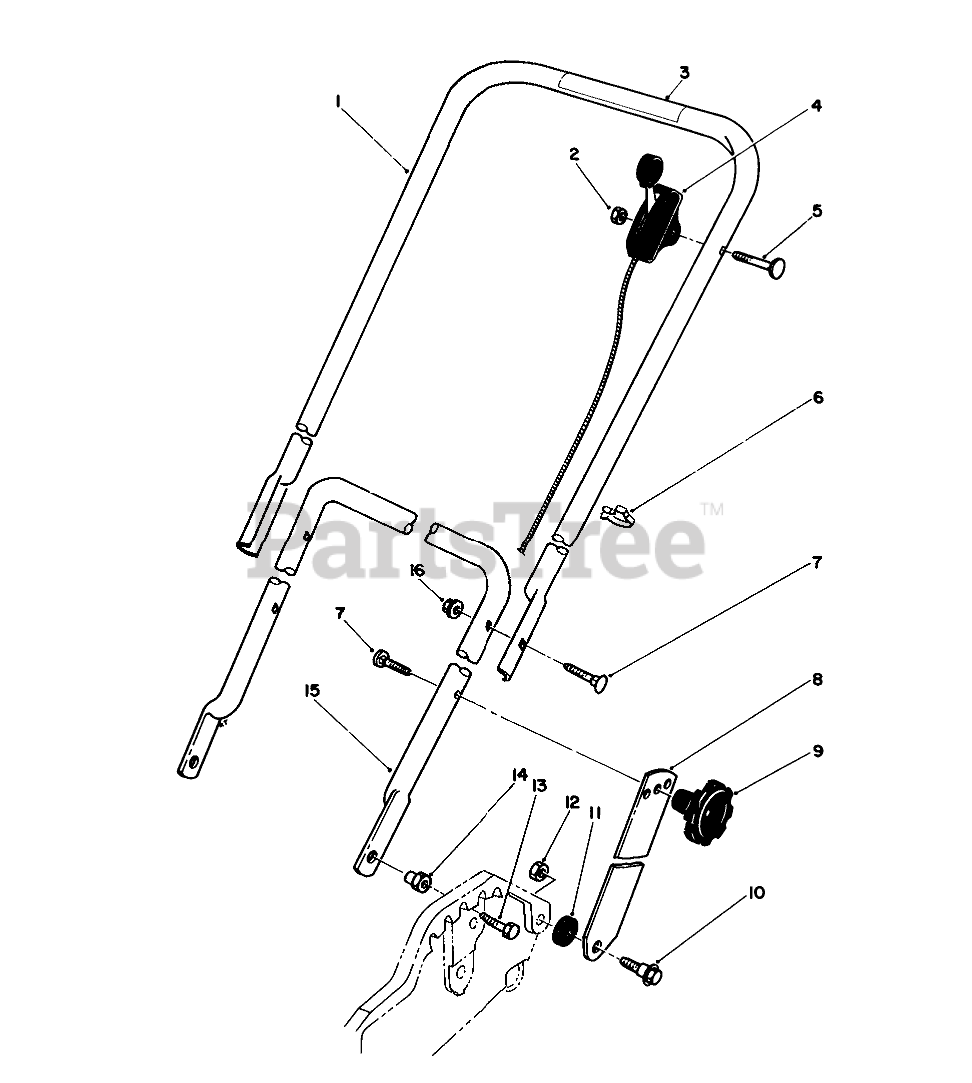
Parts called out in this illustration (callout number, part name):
1	Handle-Upper (Incl. Ref. #3)
2	NUT-LOCK, NI
3	Decal-Danger
4	Throttle Control
5	SCREW-HANDLE
6	BOWDEN CLIP
7	SCREW
8	Handle Latch
10	SCREW-SHOULDER
11	SPACER
12	NUT-LOCK, NI
13	SCREW-HH
14	HANDLE PIVOT NUT
15	LOWER HANDLE
16	NUT-LOCK, NI
